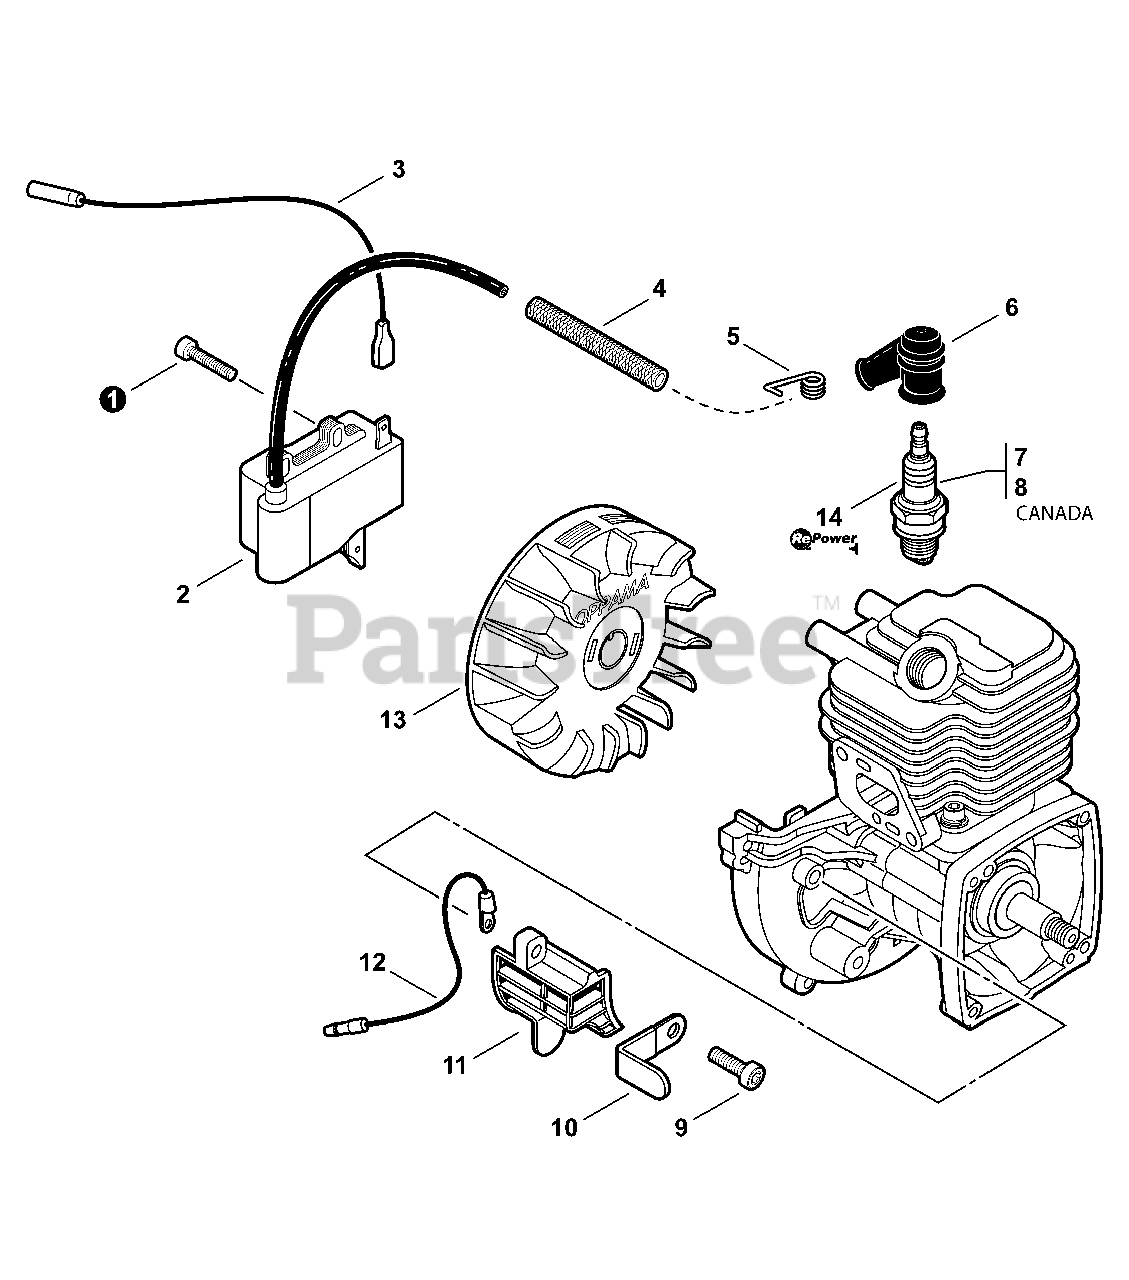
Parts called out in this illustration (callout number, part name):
1	SCREW - 4×20 -- TORX
2	COIL, IGNITION
3	LEAD - IGNITION
4	TUBE, INSULATOR
5	TERMINAL, SPARK PLUG CAP
6	CAP, SPARK PLUG
7	SPARK PLUG -- BPM8Y
8	SPARK PLUG -- BPMR8Y
9	SCREW - 5×16
11	COVER, DEBRIS
12	LEAD - GROUND
13	FLYWHEEL
14	RePower TUNE-UP KIT
